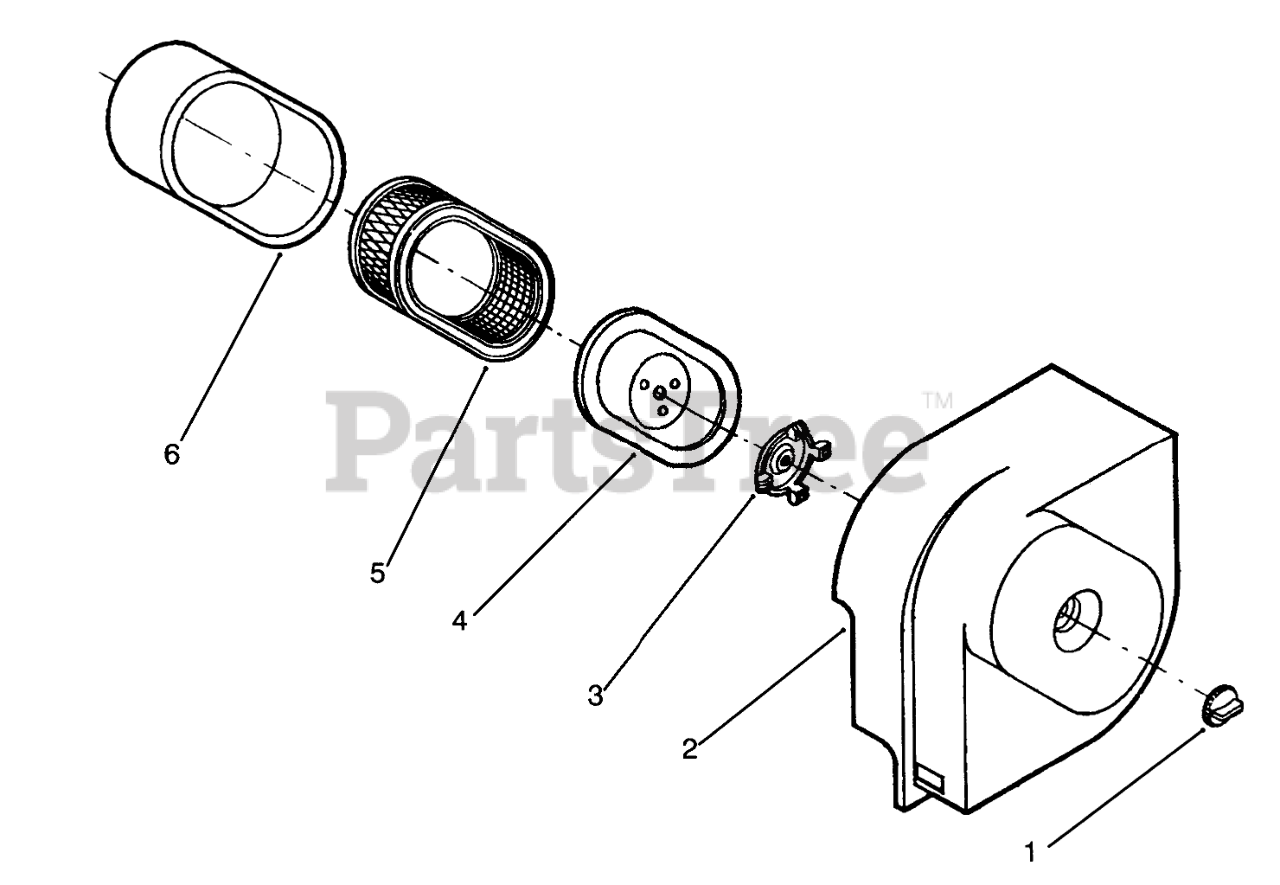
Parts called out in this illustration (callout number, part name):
1	KNOB-TOOL LESS
2	AIR CLEANER COVER
3	INNER COVER KNOB
4	ELEMENT COVER
5	AIR CLEANER ELEMENT
6	FLTR ELEMENT WRAPPER
